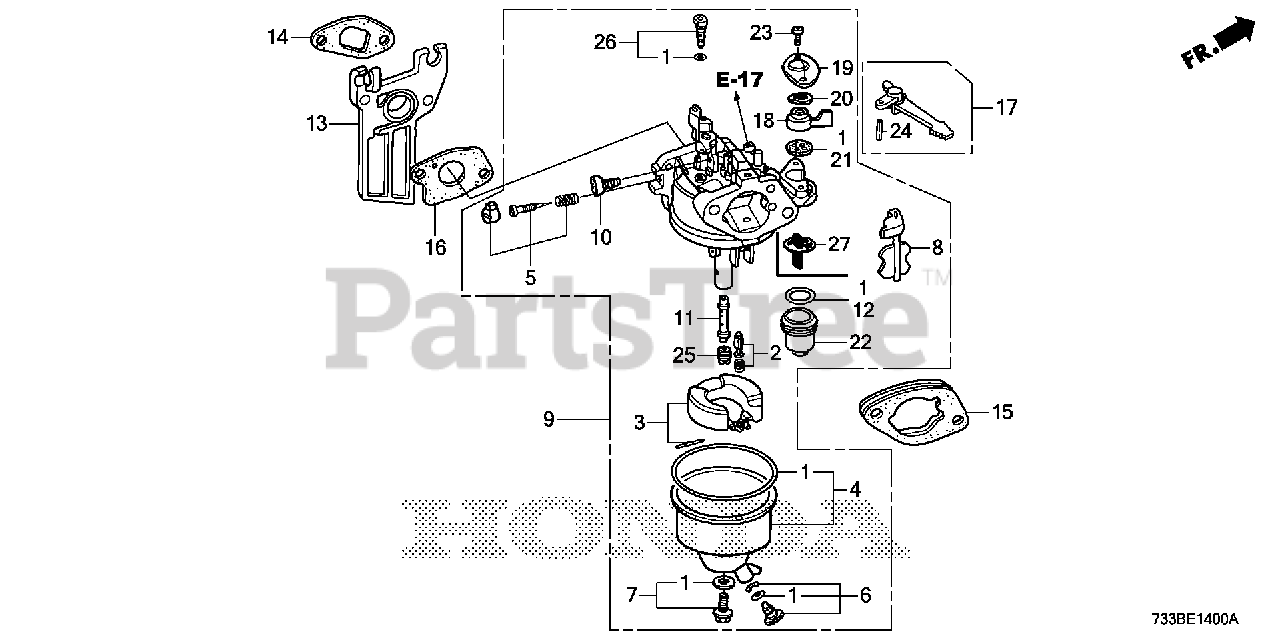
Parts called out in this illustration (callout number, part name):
1	GASKET SET (CARBURETOR NO.)
2	VALVE SET, FLOAT (CARBURETOR NO.) (SEAT NOT INCLUDED)
3	FLOAT SET
4	CHAMBER SET, FLOAT
5	SCREW SET (Honda Code 4219879). (CARBURETOR NO.)
6	SCREW SET, DRAIN (CARBURETOR NO.)
7	SCREW SET
8	CHOKE SET
9	CARBURETOR ASSY. (BE65F B)
10	SCREW, THROTTLE STOP
11	NOZZLE, MAIN (CARBURETOR NO.)
12	GASKET, FUEL STRAINER CUP
13	INSULATOR, CARBURETOR
14	GASKET, INSULATOR
15	SPACER, CARBURETOR
16	GASKET, CARBURETOR
17	LEVER, CHOKE (STD)
18	LEVER, VALVE
19	PLATE, LEVER SETTING (CARBURETOR NO.)
20	SPRING, PETCOCK LEVER (CARBURETOR NO.)
21	GASKET, VALVE
22	CUP, FUEL STRAINER
23	SCREW, PAN (3X6)
24	PIN, SPRING (2X12)
25	JET, MAIN (#65)
25	JET, MAIN (#68)
25	JET, MAIN (#70)
26	JET SET, PILOT (#38)
